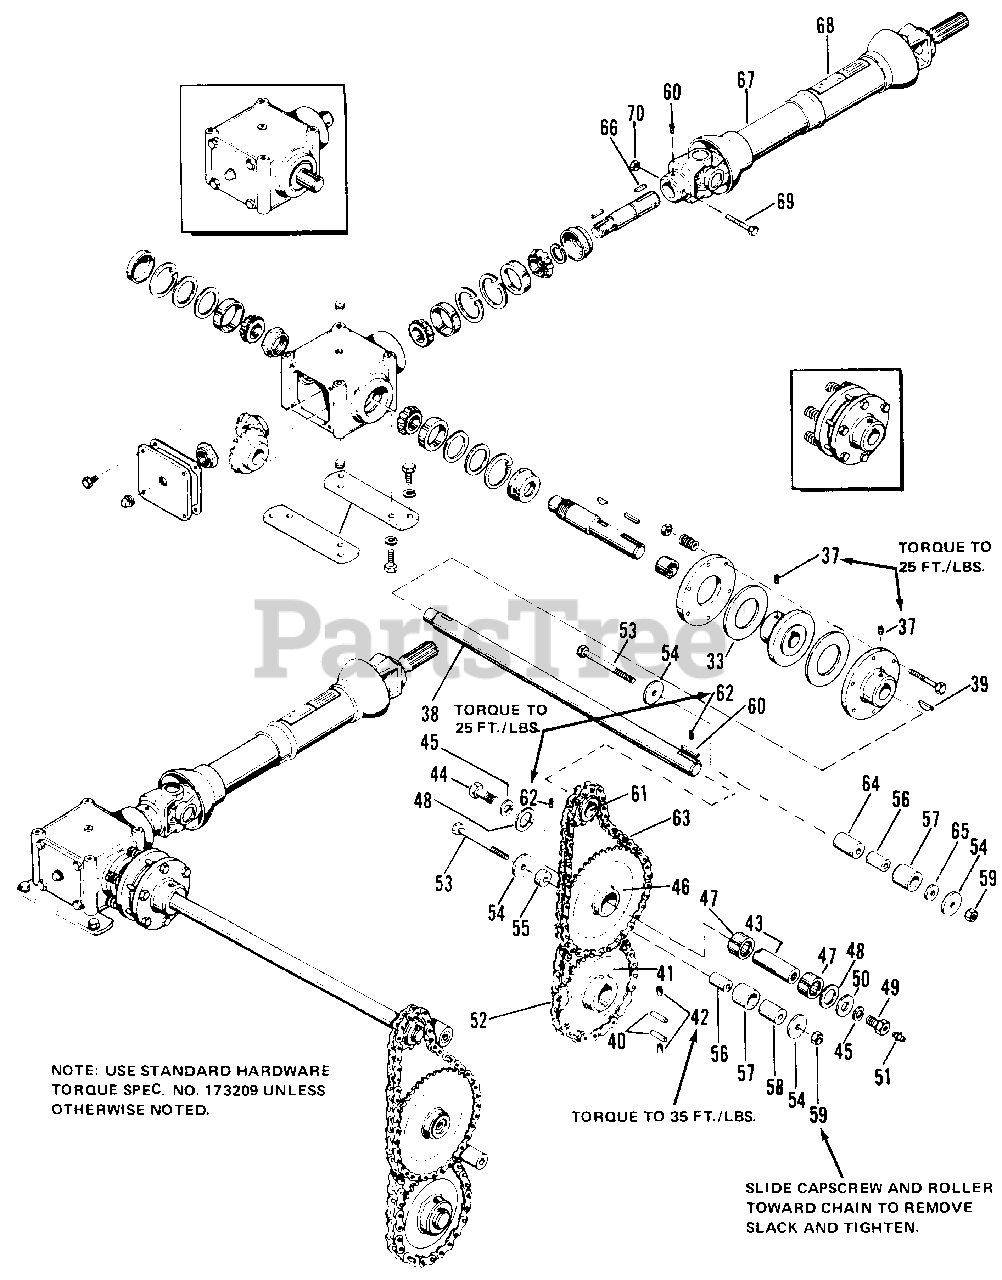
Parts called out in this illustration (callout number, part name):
37	SCREW, Set, Sq., Hd., Cup Pt., 5/16-18 x 1/2, Gr. 8
39	KEY, Hi-Pro
41	SPROCKET ASSY
42	SCREW, Set, Sq. Hd., Cup pt., 3/8-16 x 3/4, Gr. 8
44	CAPSCREW, Hex Hd., 1/2-20 x 1-1/4
45	LOCKWASHER, Spring, 1/2
46	SPROCKET ASSY
47	BEARING, Pulley
49	BOLT, Side, R.H.
50	WASHER, Plain, 1/2
51	FITTING, Lube, 1/4-28
52	CHAIN, Roller
53	CAPSCREW, Hex Hd., 3/8-16 x 4
54	WASHER
59	NUT, Hex, Full Lock, 3/8-16
60	SCREW, Set, Sq. Hd., Cup Pt., 5/16-18 x 1/2, Gr. 8
61	SPROCKET ASSY
62	SCREW, Set, Sq. Hd., Cup Pt., 5/16-18 x 3/8, Gr. 8
63	CHAIN, Roller
67	DRIVE ASSY, PTO
68	DECAL, PTO
69	CAPSCREW, Hex Hd., 1/4-20 x 2-1/4
70	NUT, Hex, Lock, 1/4-20
